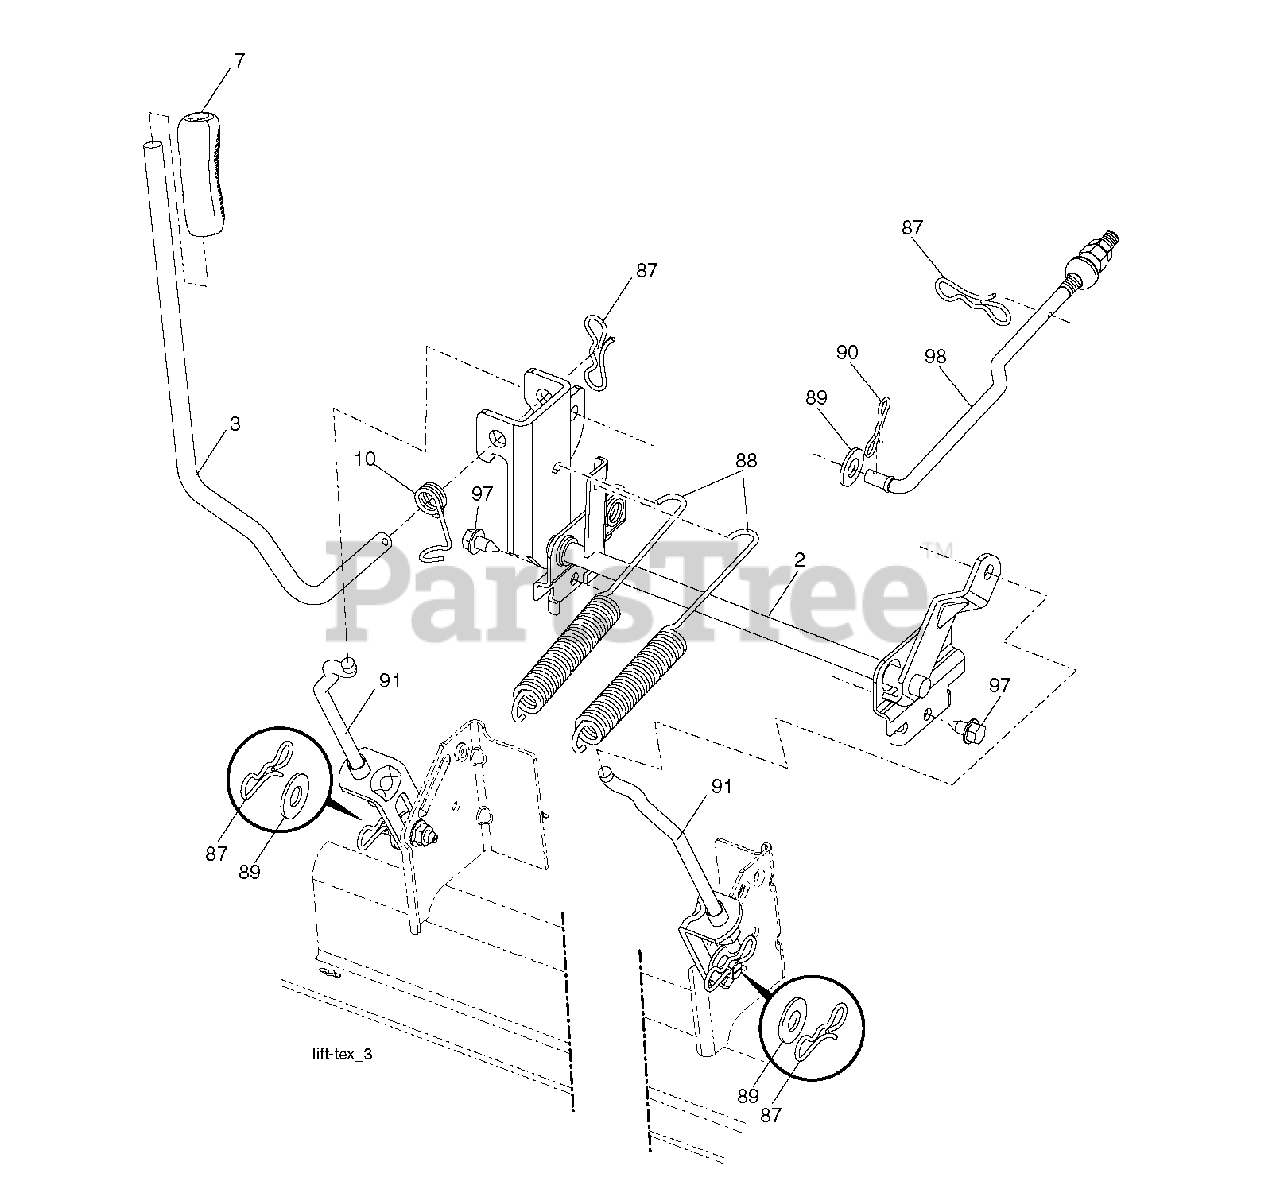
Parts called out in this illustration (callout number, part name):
2	SHAFT.ASM.LIFT.CROSS.H
3	LEVER.LIFT.HANDLE.GT
7	GRIP.HANDLE.LIFT.PVC.BLACK
10	SPRING.TORSION.LIFT.HANDLE
87	PIN.COTTER.7/16.BOW TI
88	SPRING.LIFT.ASSIST.GT2
89	WASHER.CLEAR.ZINC
90	PIN.COTTER.5/16.BOW TI
91	LINK.LIFT.ASM.REAR.GT.
97	SCREW, 3/8-16X3/4
98	LINK.ASM.SUSP.FRONT.MWR.10.5
